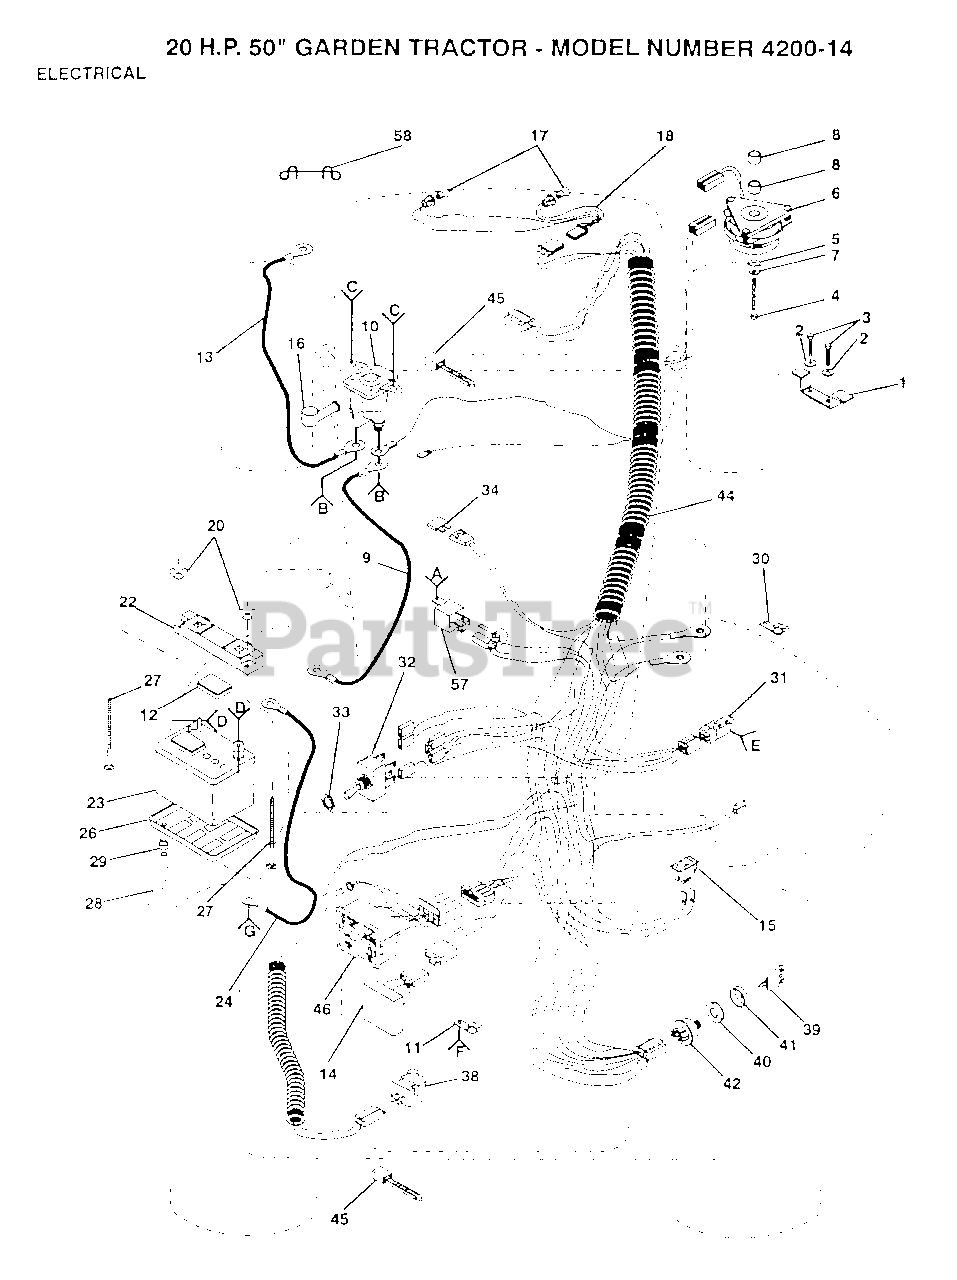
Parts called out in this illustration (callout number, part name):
2	LOCKWASHER
3	BOLT
5	WASHER
7	LOCKWASHER
8	SPACER-CLUTCH
9	CABLE-BATTERY T
12	"CAP,BATTERY "
14	SENSOR LOW VOLT T
15	SWITCH LT
24	CABLE T
26	"TRAY T, BATTERY"
27	BOLT
29	HOSE CLAMP T
30	CLIP GTV
31	SWITCH INTERLOCKT
33	HEX NUT T
34	FUSE HYT
35	"NUT,KEPS"
38	SWITCH SEAT
39	KEY
45	WIRE TIE
46	INDICATORLIGHTT
48	NUT
49	SCREW ST
50	BOLT LT
51	WASHER
52	LOCKWASHER
54	SCREW
57	RELAY ASSY T
58	TIE WIRE
59	LOCKWASHER
